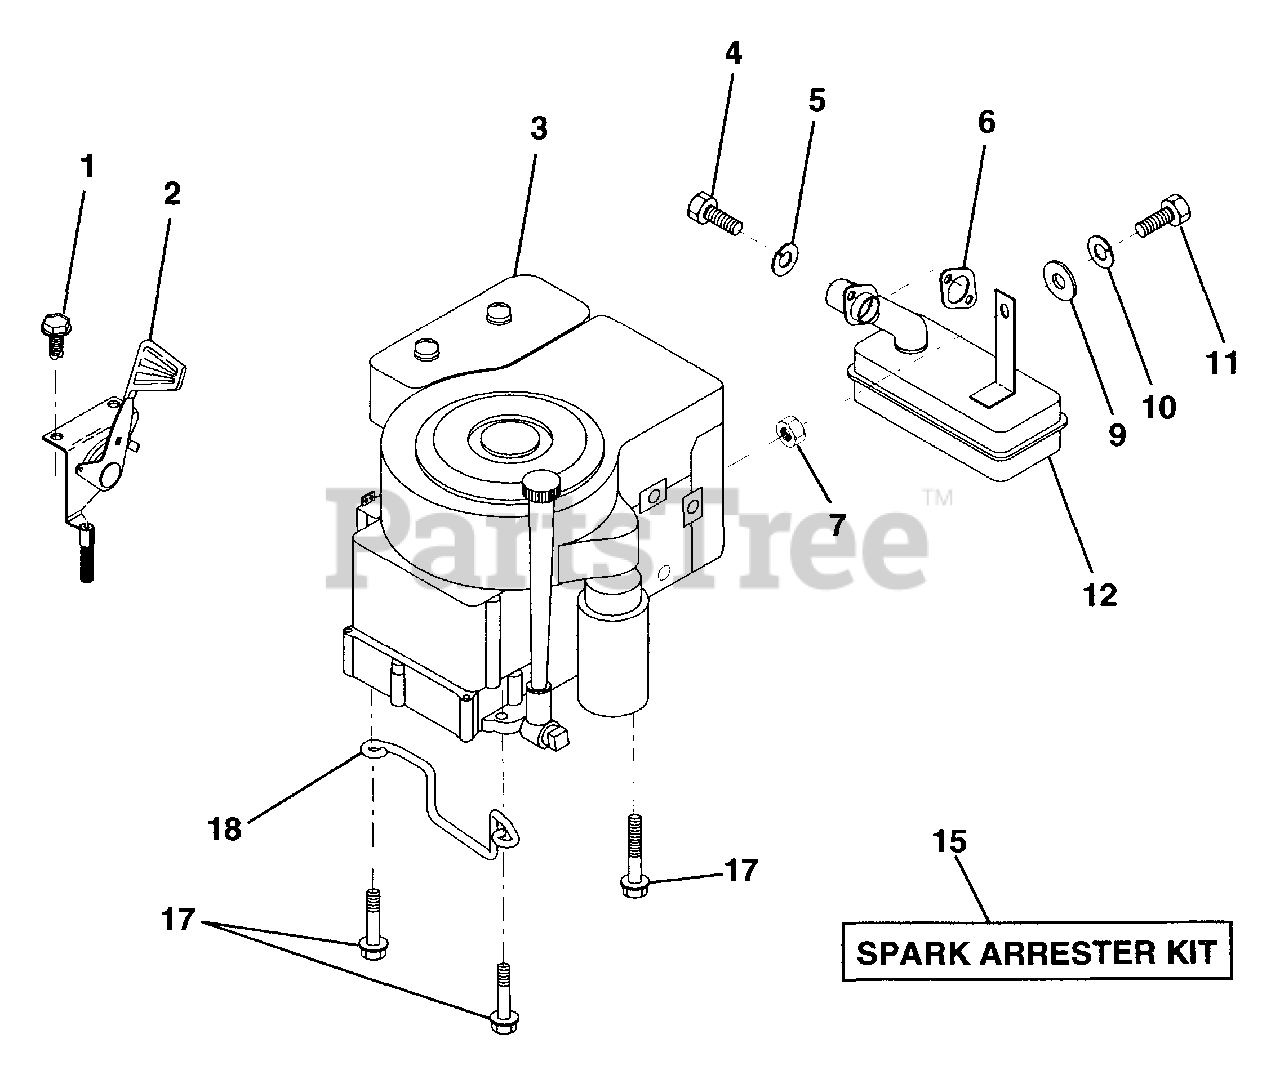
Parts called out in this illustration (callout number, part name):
1	Screw, Hex Head, Thread-Cutting 1/4-20 x 1/2
2	Control, Throttle
3	Engine, Briggs and Stratton
4	Screw, Hex Cap Head 5/16-18 x 3/4
5	Washer, Lock, Heavy Helical Spring 5/16
6	Gasket, Exhaust
7	Nut Fin H 5/16 - 18
9	Washer 5/16 x 3/4 x 16 Gauge
10	Washer, Lock, Heavy Helical Spring 1/4
11	Bolt, Hex, Fin. 1/4-20 UNC x 1
15	Arrester, Spark
17	Screw, Hex Washer Head, Thd., Roll. 3/8-16 x 1-1/2
18	Keeper, Ground Drive Belt
